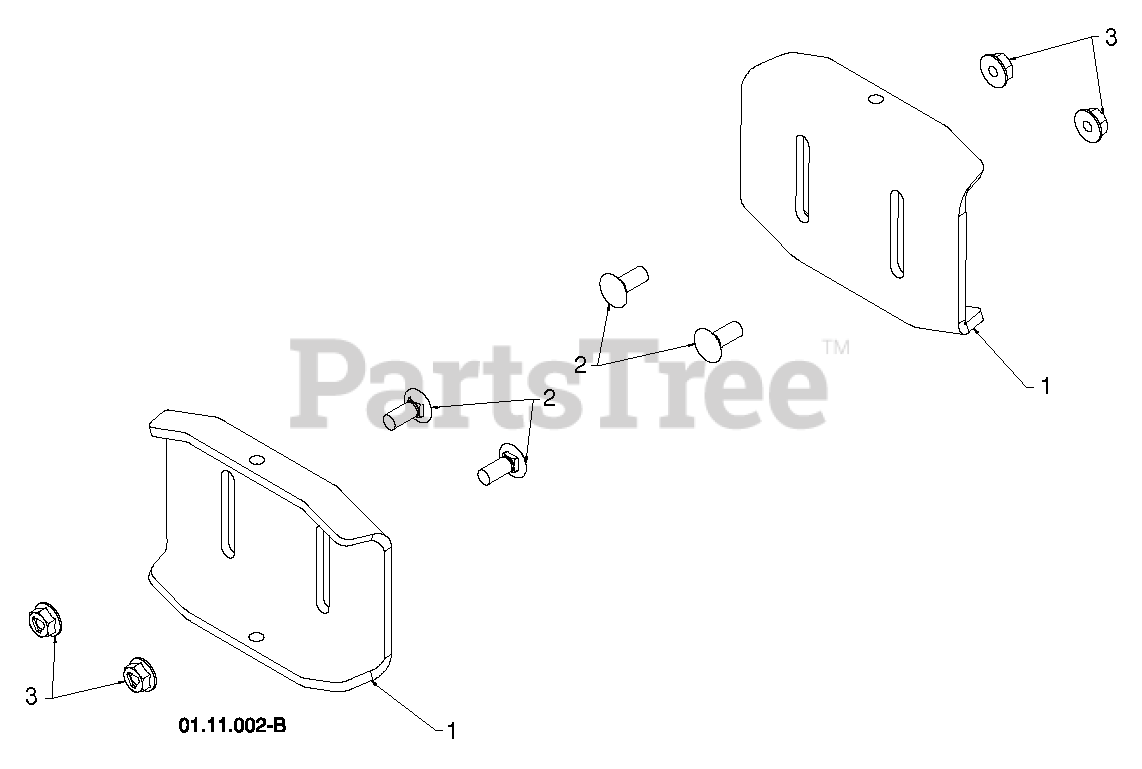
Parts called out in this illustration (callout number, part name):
1	SKID PLATE
2	BOLT
3	NUT.LOCK.5/16-18
